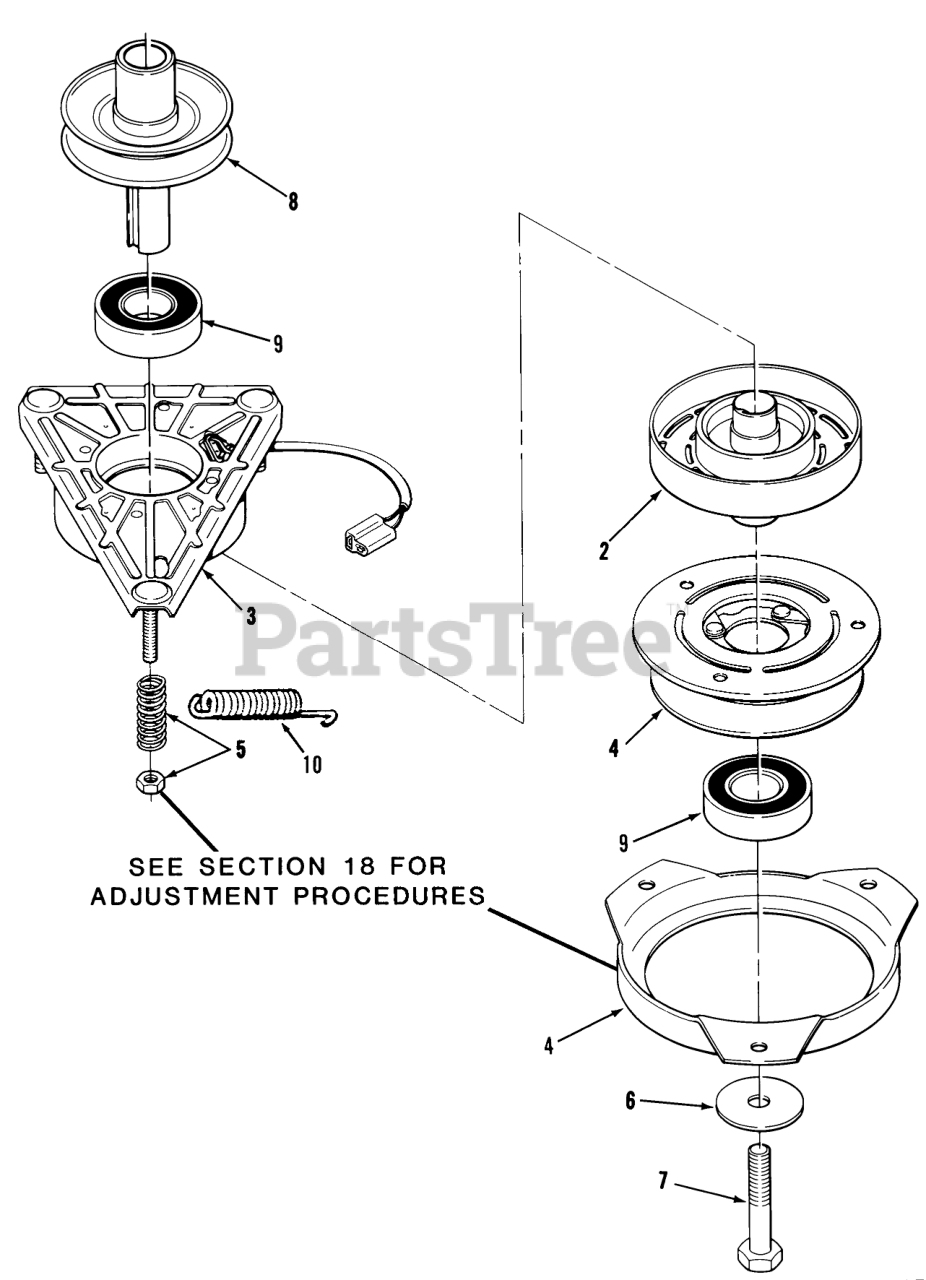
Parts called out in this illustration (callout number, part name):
2	ASS'Y-ROTOR
3	Field Assy (includes one of item 9)
4	Armature and Pulley Assy (includes one of item 9 and Brake Plate)
5	ACCESS SPRING & NUT
6	WASHER
7	HHCS M10X1.5X120
8	PULLEY-ENGINE
9	BEARING-ELEC CLUTCH
10	Spring
